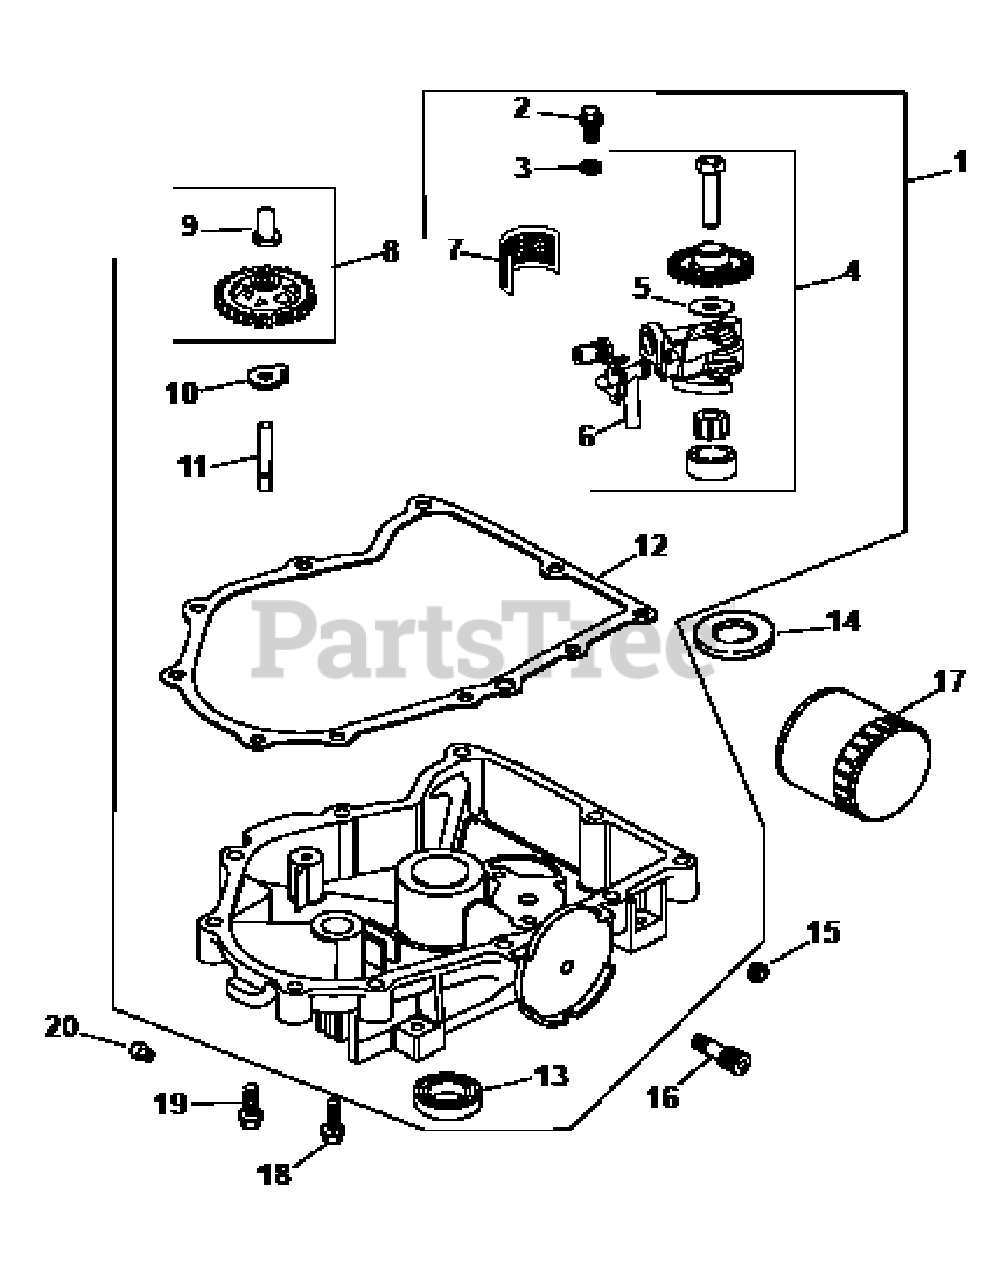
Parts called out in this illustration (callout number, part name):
1	Oil Pan w/Gasket Kit
2	Hex Flange Screw
3	Plain 6mm Washer
4	Oil Pump Assy.
5	Oil Pump O-Ring
6	Oil Pickup Tube
8	Governor Gear w/Pin Kit
12	Oil Pan Gasket
13	Oil Seal (PTO Side)
16	Oil Filter Nipple
17	Oil Filter
18	Hex Flange Screw
19	Hex Flange Screw (M6 x 1.0 x 25)
